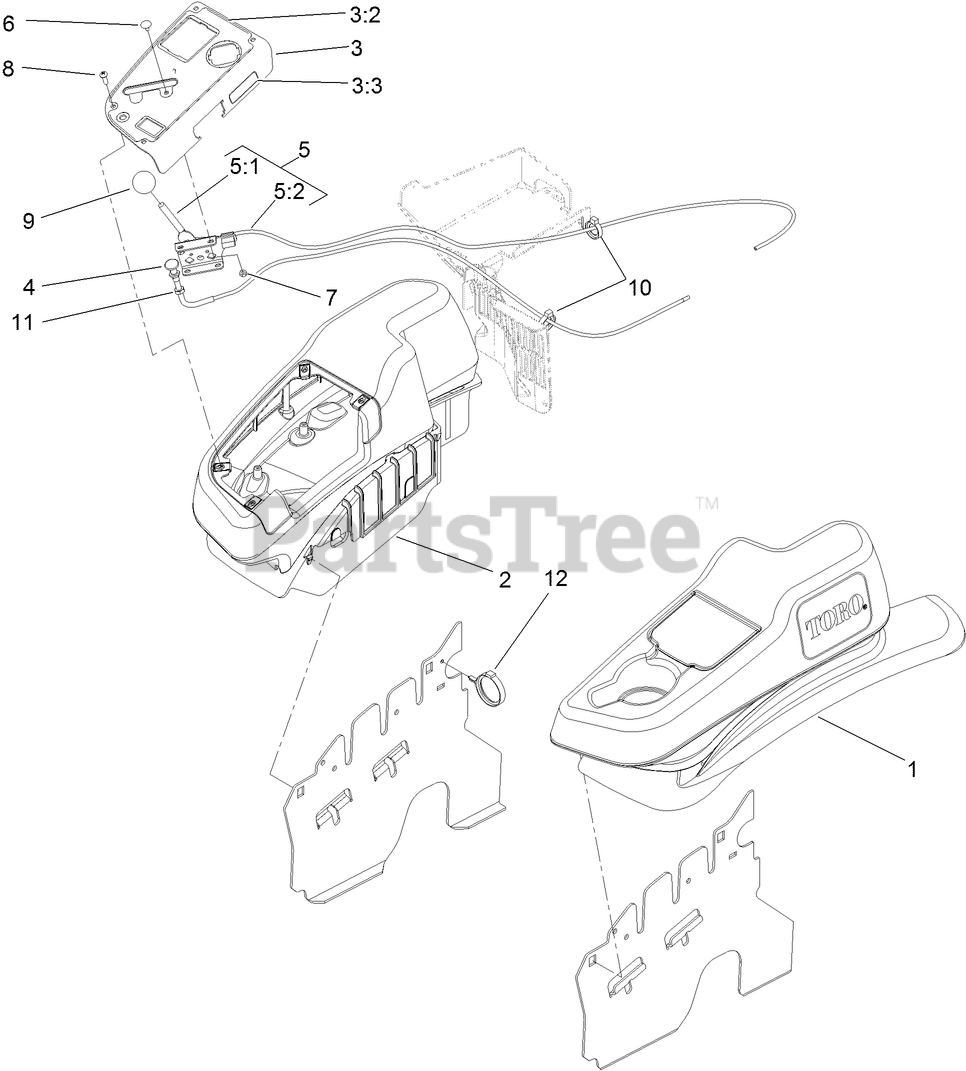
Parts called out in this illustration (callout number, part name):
1	LH NARROW FENDER/CONSOLE ASM
2	RH NARROW FENDER/CONSOLE ASM
3	CONTROL PANEL ASM
3:2	DECAL-CONTROL PANEL
3:3	DECAL-FUSES
4	CHOKE CONTROL ASM
5	THROTTLE CONTROL ASM
5:1	LEVER-THROTTLE
5:2	CABLE-THROTTLE
6	BOLT-CARR
7	NUT-LOCK, NI
8	SCREW-HWH
9	KNOB-BALL
10	CLAMP-HOSE
11	NUT-HJ
12	CLAMP-HARNESS
